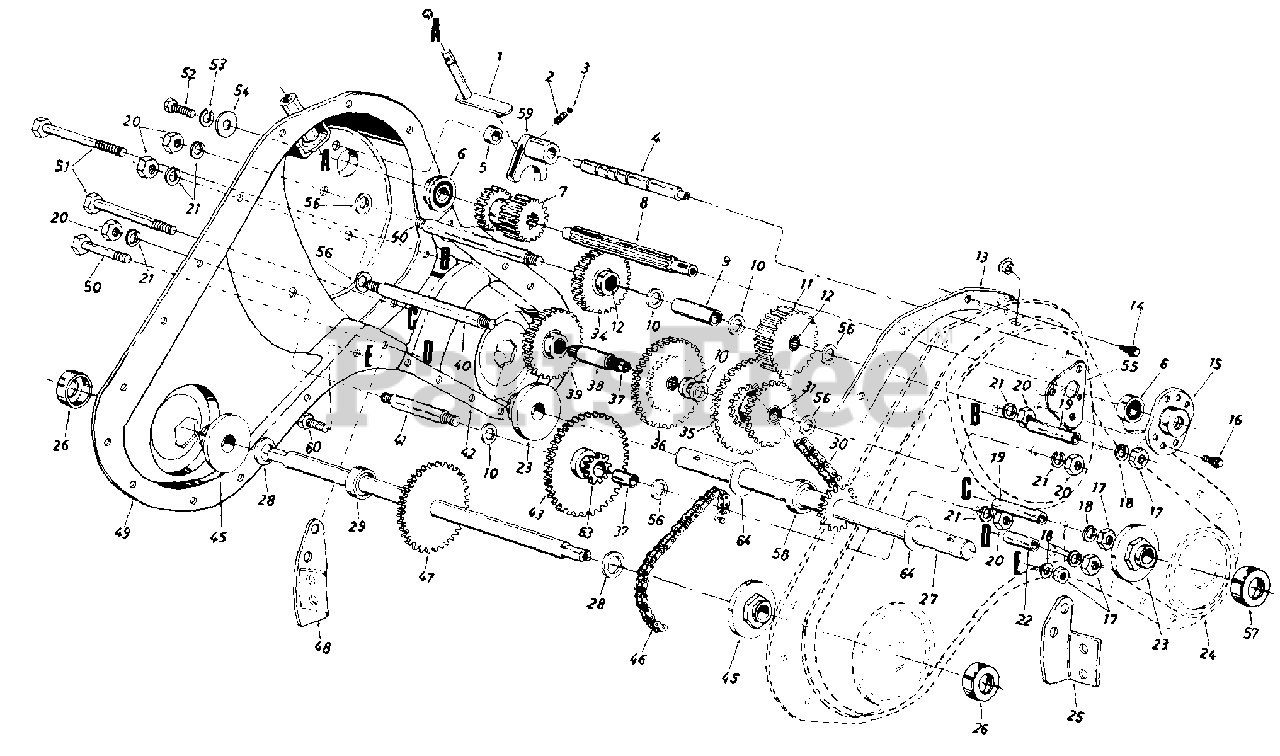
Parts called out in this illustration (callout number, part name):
1	Shifting Bracket Ass'y.
2	Compression Spring .50" Lg.
3	Ball Detent .250" Dia.
4	Detent Shaft 1/2" Dia.
5	Spacer .505" I.D. x .88" O.D.
6	Ball Brg. .62" I.D. x 1.38"
7	Spur Gear 16T
8	Input Spline Shaft 7/8"
9	Spacer .657" I.D. x 2.85" Lg.
10	Fl-Wash. .640" I.D. x 1.24"
11	Spur Gear 30T 7/8" I.D.
12	Needle Bearing 5/8" I.D.
13	Gasket--Trans. Hsg.
14	Hex S-Tap Scr. 1/4-20 x .5"
15	1-3/8" Dia. Bearing Housing
16	Hex TT-Tap Scr. 1/4-20 x .75"
17	Hex Nut 5/16-18 Thd.
18	L-Wash. 5/16" I.D.
19	Spacer 1.56" Lg.
20	Hex Nut 7/16-20 Thd.
21	Bell-Wash. .45" I.D. x 1.0"
22	Spacer 1.015" Lg.
23	Tine Shaft Brg. 1.002 x 2.50
24	Trans. Housing Ass'y.--L.H.
27	Tine Shaft Ass'y. 1" O.D.
28	Fl-Wash. .76" I.D. x 1.5" O.D.
29	Spacer .75" I.D. x .50" Lg.
30	Chain #50 5/8 Pitch x 52 Links--Endless
31	Needle Bearing 5/8" I.D.
34	Spur Gear 30T 12/16" I.D.
35	30/44T Gear Ass'y. Comp.
36	Spur Gear 44T
37	Sleeve Bearing
38	Gear Hub 3/4" I.D. x 3" Lg.
39	Spur Gear 30T 1.0" I.D. x 1/2" W
40	Jack Shaft 5/8" Dia. x 5"
41	Jack Shaft 5/8" Dia. x 2.38"
45	Wheel Brg. .752" x 2.5"
46	#420 Chain 1/2 Pitch x 50 Links--Endless
47	Wheel Shaft Ass'y. 15.6"
51	Hex Bolt 5/16-18 x 2.5"
52	Hex Bolt 1/4-20 x .62" Lg.
53	L-Wash. 3/8" I.D.
54	Fl-Wash. 1/4" I.D. x .93" O.D.
55	Gear Positioner Bracket
56	Fl-Wash. 7/16" I.D. x 1-3/8"
57	Dust Cover Ass'y. 1" Shaft
58	Spacer 1" I.D. x 2" O.D.
59	Shifting Fork
60	Hex Bolt 5/16-18 x .75" Lg.
63	10T Sprocket Ass'y.
64	Thrust Wash. 1.03" I.D. x 1.62" O.D.
